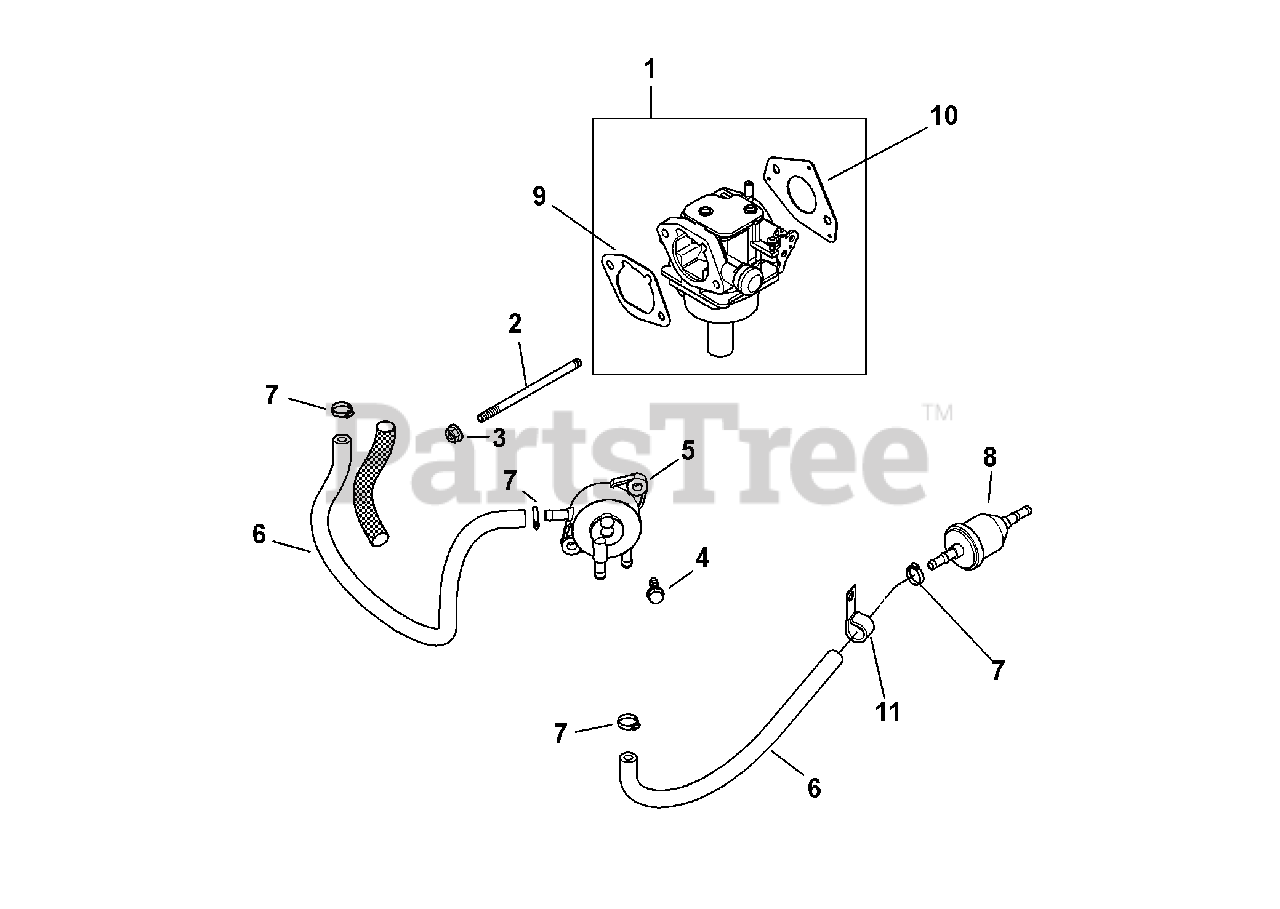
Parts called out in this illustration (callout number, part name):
1	Carburetor Kit
2	Stud, M6 x 1.0 x 106
3	Flange Nut, M6 x 1.0
4	Tap Screw, M6 x 1.7 x 18
7	Hose Clamp, 1/2
9	Air Cleaner Base Gasket
10	Carburetor Gasket
